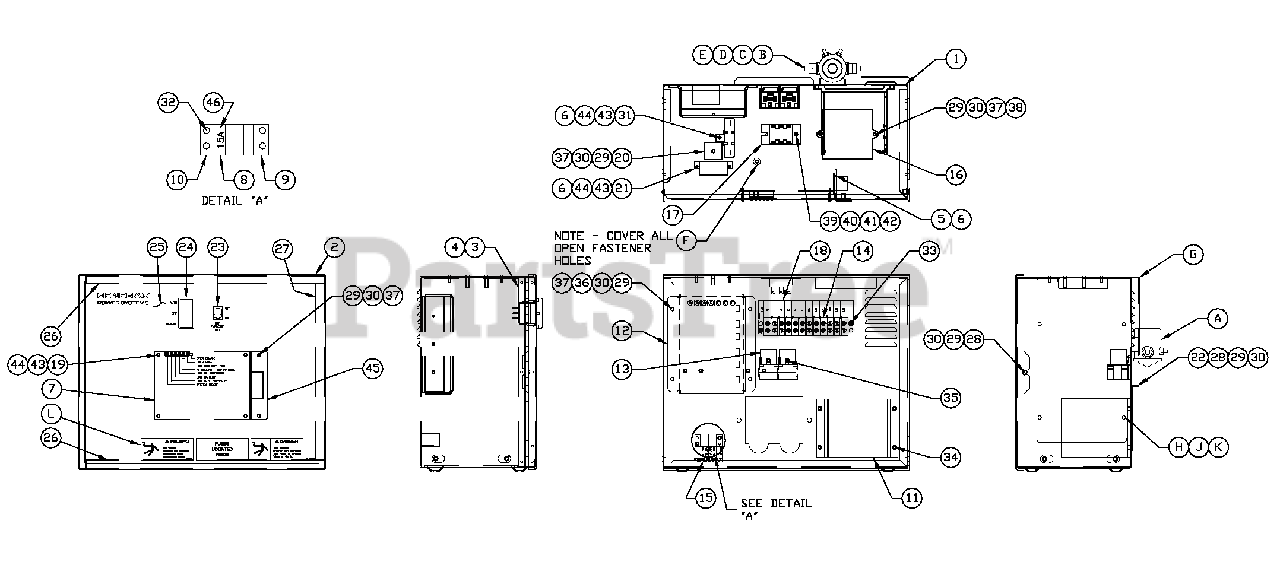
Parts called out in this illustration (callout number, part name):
1	ENCL HSB CONTROL PANEL
2	COVER CONTROL PANEL
3	HINGE CONTINUOUS H-PANEL
4	RIVET POP .125 X .275 SS
5	SCR EW PHM M3-0.5X 10MM
6	W A SH ER FLAT M3
7	A S SY PCB CPL2 CTRLR 3600 RPM
8	HOLDER, FUSEWICKMANN 178.6150
9	ADPTR.RH SIDEWICKMAN 178.6191
10	ADPTR,LH SIDEWICKMAN 178.6192
11	A S SY PCB 2AMP 12V UL BATT CHGR
12	A S SY VOLTAGE REGULATOR 60HZ
13	RELAY, 12VDC C FORM W/DIODE
14	BLOCK TERM 20A 12 X 6 X 1100V
15	DECAL CPL CONTROL PANEL FU SE S
16	A S SY PCB BOSCH GOV DRIVER
17	A S SY PCB SCR BRIDGE
18	DECAL CPL 3.9LTB1
19	S PA C ER 9.5H 3.2 ID
20	DIO BRIDGE 25A 600V
21	CIRCT B R K 7 X 1 ETA 46-500-P
22	PLATE,HARNESS CLAMP
23	SWITCH RKR DPST 125V SPD
24	SWITCH RKR DPDT ON-OFF-ON
25	DECAL, CONTROL HSB
26	S EA L COVER 3.18X12.7X382
27	S EA L COVER 3.18X12.7X283
28	SCR EW HHPM M5-0.8 X 12
29	W A SH ER FLAT M5
30	W A SH ER LOCK M5
31	R ES WW 15R 5% 25 W QK CONN
32	SCR EW PHTT M3.5-0.6 X 10
33	SCR EW PHTT M3.5-0.6 X 16
34	SCR EW PHTT M4-0.7 X 12 ZYC
35	SCR EW PHTT M4-0.7 X 10 ZYC
36	SCR EW PPHM M5-0.8 X 12 ZNC
37	NUT HEX M5-0.8 G8 CLEAR ZINC
38	SCR EW PPHM M5-0.8 X 30 SS
39	SCR EW PPHM M4-0.7X 16
40	W A SH ER FLAT M4
41	W A SH ER LOCK #8-M4
42	NUT HEX M4-0.7 G8 Y E L CHR
43	W A SH ER LOCK M3
44	NUT HEX M3-0.5 G8 Y E L CHR
45	SUPPORT ANGLE PCB
46	FUSE ATO TYPE 15 AMP (BLUE)
47	HARN 3600RPM R200 CONTROL PNL
A	RELAY SOLENOID 12VDC PNL MNT
B	SCR EW HHC 1/4-20 X 3/4 G5
C	W A SH ER FLAT 1/4-M6 ZINC
D	W A SH ER LOCK M6-1/4
E	NUT HEX 1/4-20 ST E E L
F	S EA L WEATHER .45"DIA
G	COVER CONTROL PANEL SIDE
H	SCR EW PPHM M5-0.8 X 12 ZNC
J	W A SH ER LOCK M5
K	W A SH ER FLAT M5
L	DANGER HIGH VOLTAGE (SPANISH)
